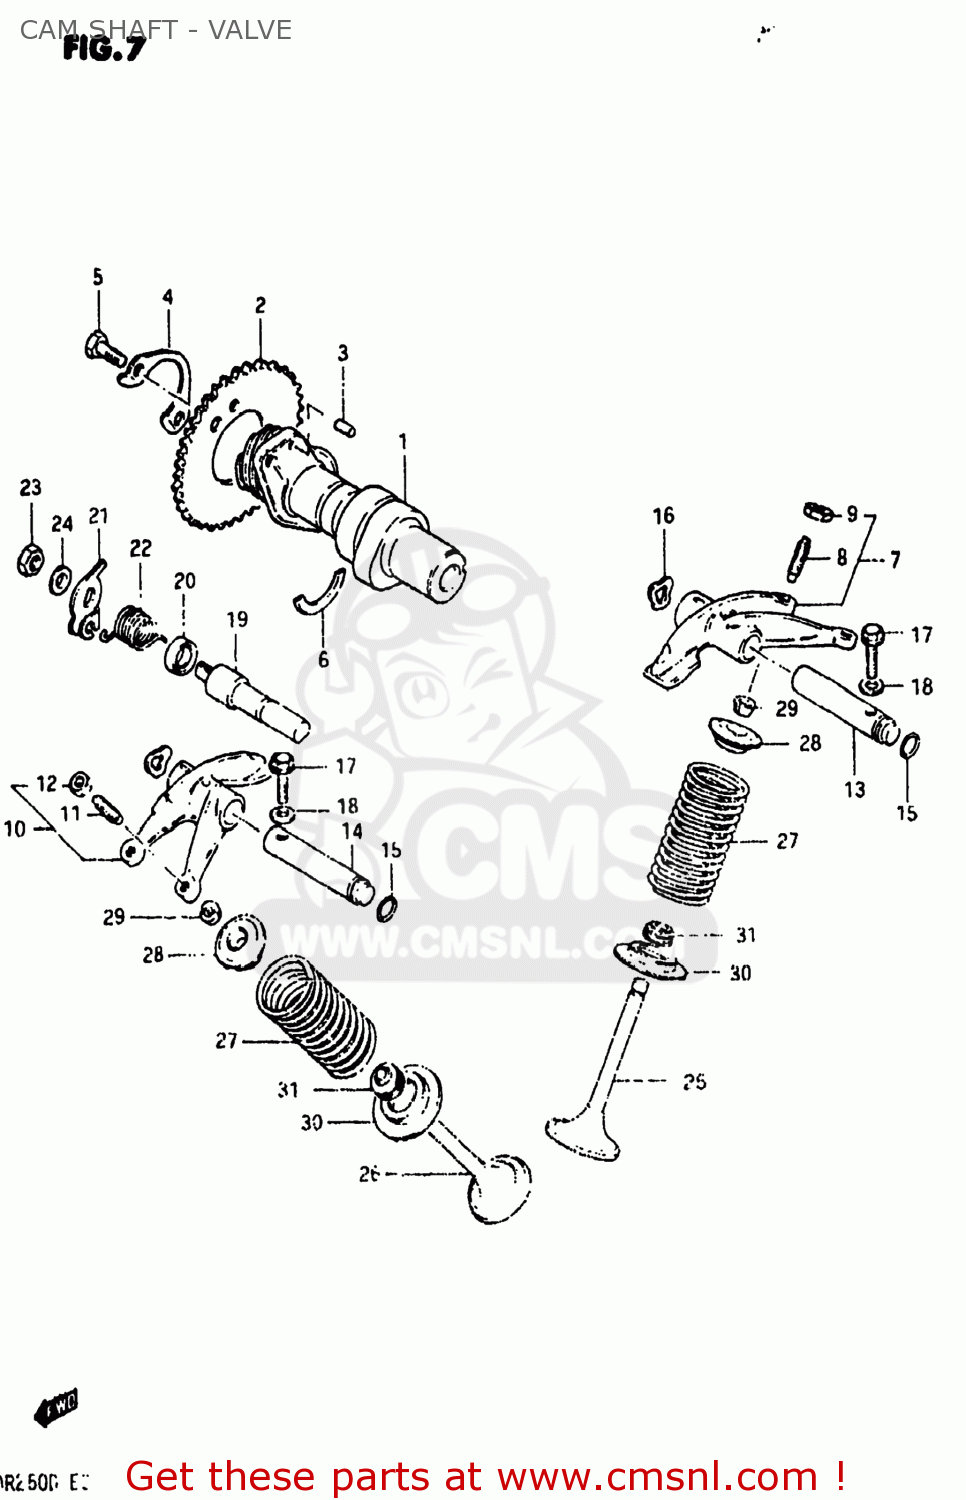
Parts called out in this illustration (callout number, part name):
1	CAMSHAFT
2	SPROCKET,CAMSHAFT(NT:42)
3	PIN
4	WASHER,CAM CHAIN SPROCKET
5	BOLT(6X12.5)
6	C RING
7	ARM,VALVE ROCKER
8	SCREW,TAPPET ADJUSTING
9	NUT,ADJUSTING
10	ARM,VALVE ROCKER,EXHAUST
11	SCREW,TAPPET ADJUSTING
12	NUT,ADJUSTING
13	SHAFT,VLV ROCKER ARM IN(L:91.5
14	SHAFT,VLV ROCKER ARM EXH(L:76)
15	O-RING
16	WASHER
17	BOLT 6X30
18	GASKET (NAS)
19	SHAFT,DECOMPRESSION
20	OIL SEAL
21	LEVER,DECOMPRESSION SHAFT
22	SPRING
23	NUT 8MM
24	WASHER,8.5X16X
25	VALVE,INTAKE
26	VALVE,EXHAUST
27	SPRING,VALVE
28	RETAINER,VALVE SPRING
29	COTTER VALVE
30	SEAT,VALVE SPRING
31	OIL SEAL
